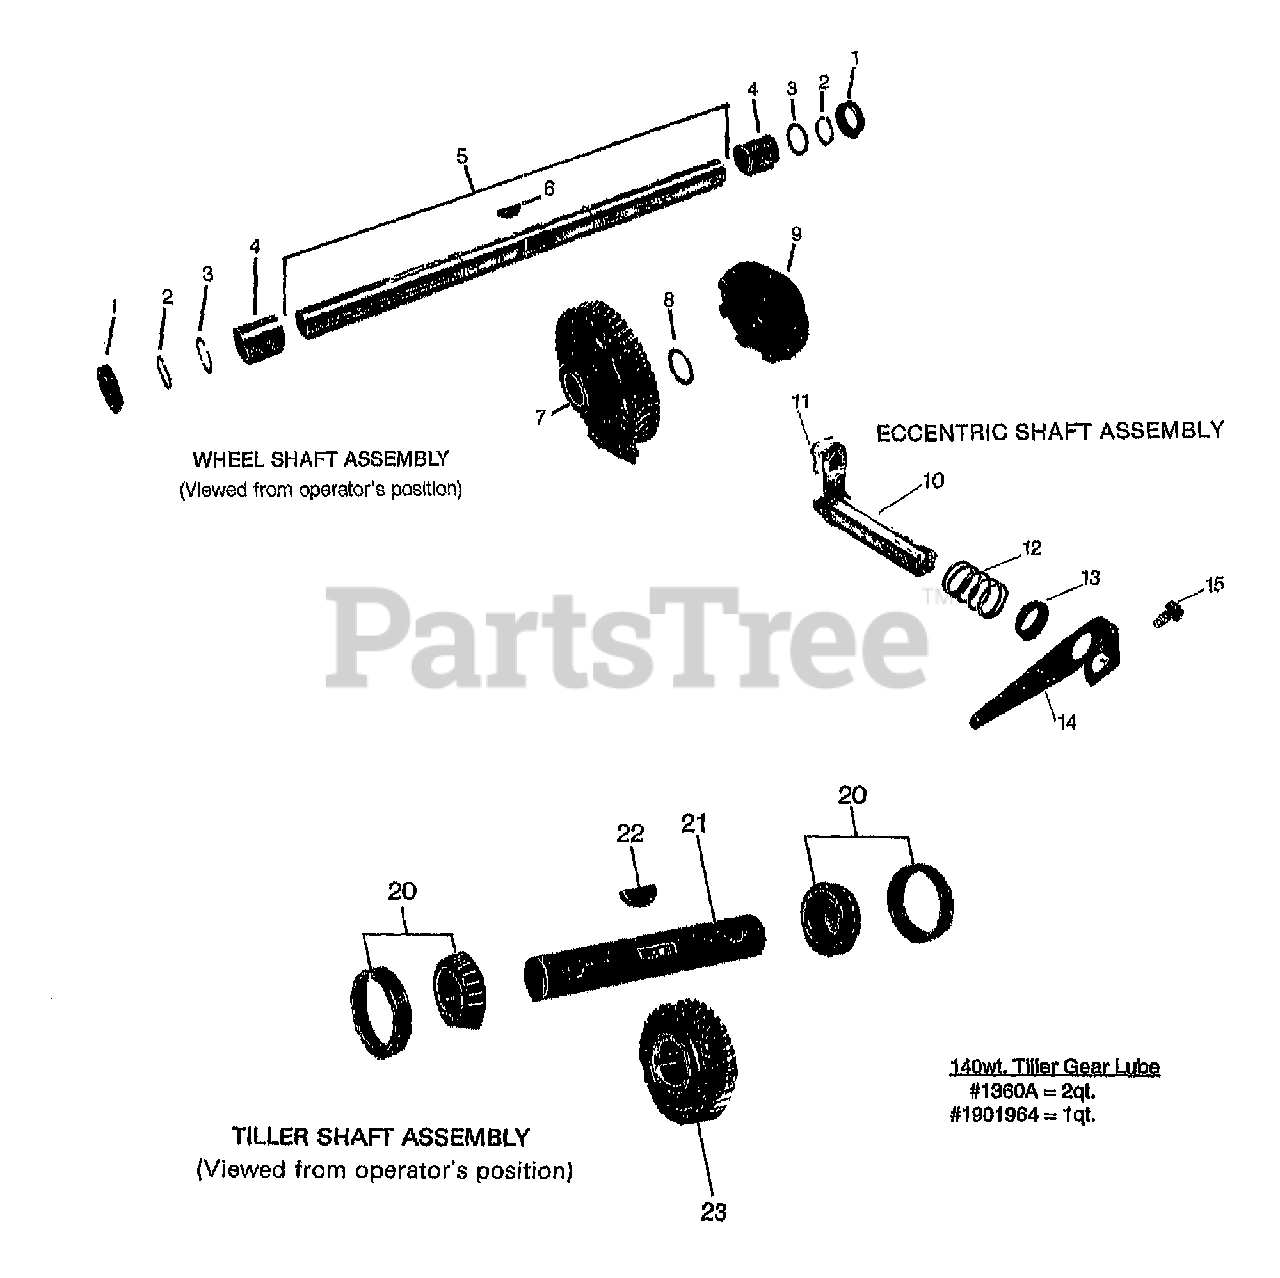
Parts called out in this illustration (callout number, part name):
1	SEAL-OIL WHEELSHAFT
2	RING-HEAVY EXT .906 ID
3	SHIM-1.375X1.015X.062
3	SHIM-1.375X1.015X.03
3	SHIM-1.375X1.015X.015
3	SHIM-1.375X1.015X.01
4	BUSHING-1.25X1.005X1.5
5	ASSM-WHEEL SHAFT W/KEY #9373
6	KEY-HI PRO .25X1.312
7	GEAR-WORM 46 TEETH MACH
8	WASHER-1.468X1.016X.062
9	CLUTCH-MACH
10	WELD-ECCENTRIC
11	PIN-.375 X .72
12	SPRING-.850 X .875 LONG
13	SEAL-OIL ECCENTRIC
14	LEVER-CABLE ADJ PNT
15	SCR-HH 1/4-20X.5 GR5 YEL
20	BRG & RACE (USE #11514 KIT)
21	ASSM-TILLERSHAFT W/KEY #1104
22	KEY-WOODRUFF .25X1.12
23	KIT-TILLER GEAR PONY 1-4
